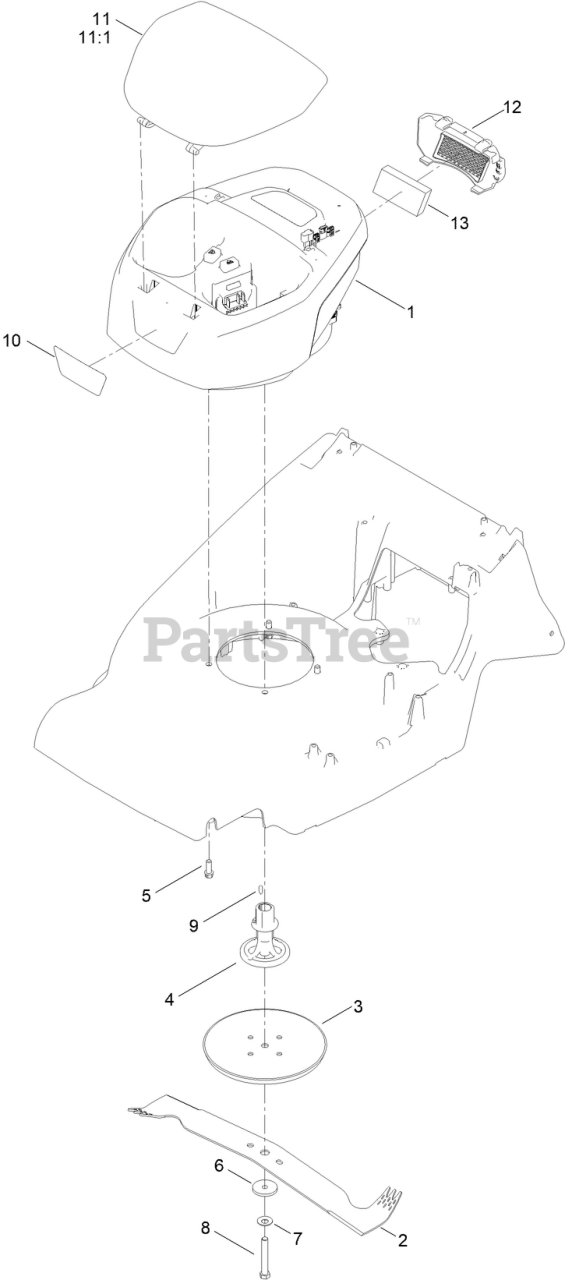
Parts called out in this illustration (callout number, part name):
1	MOTOR MODULE (60V) [DOUBLE][TORO]
2	CUTTERBAR, 56CM
3	DISC-FRICTION
4	BOSS AUTODRIVE, 22MM
5	SCREW-TAPTITE
6	SPACER-DISTANCE, CUTTERBAR
7	WASHER-LOCK
8	BOLT, UNF 3/8 X 3 (GRADE 8, ROHS)
9	KEY-FLAT
10	DECAL - FRONT MOTOR COVER
11	LID, HOUSING
12	COVER, REAR
13	FOAM, FILTER
